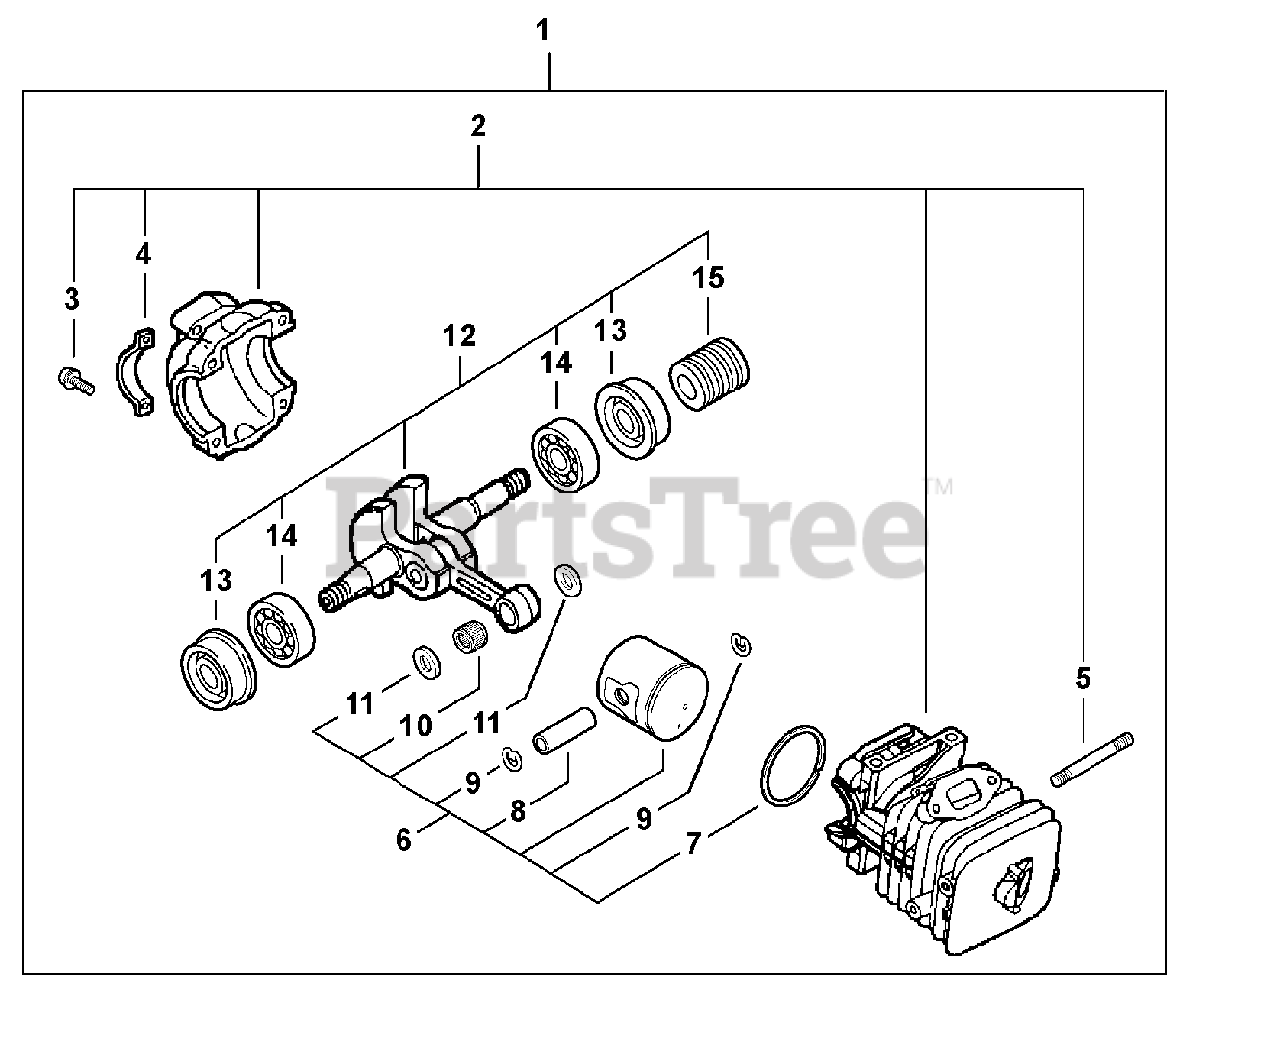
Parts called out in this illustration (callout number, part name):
1	SHORT BLOCK
2	CRANKCASE KIT
3	SCREW 5×25
4	BRACKET, CRANKCASE
5	BOLT, STUD
6	PISTON KIT
7	RING, PISTON
8	PIN, PISTON
9	RING, SNAP
10	BEARING, NEEDLE 8
11	WASHER, THRUST
12	CRANKSHAFT ASSY
13	SEAL, OIL 12
14	BEARING, BALL - 6201 C3
15	GEAR, WORM
